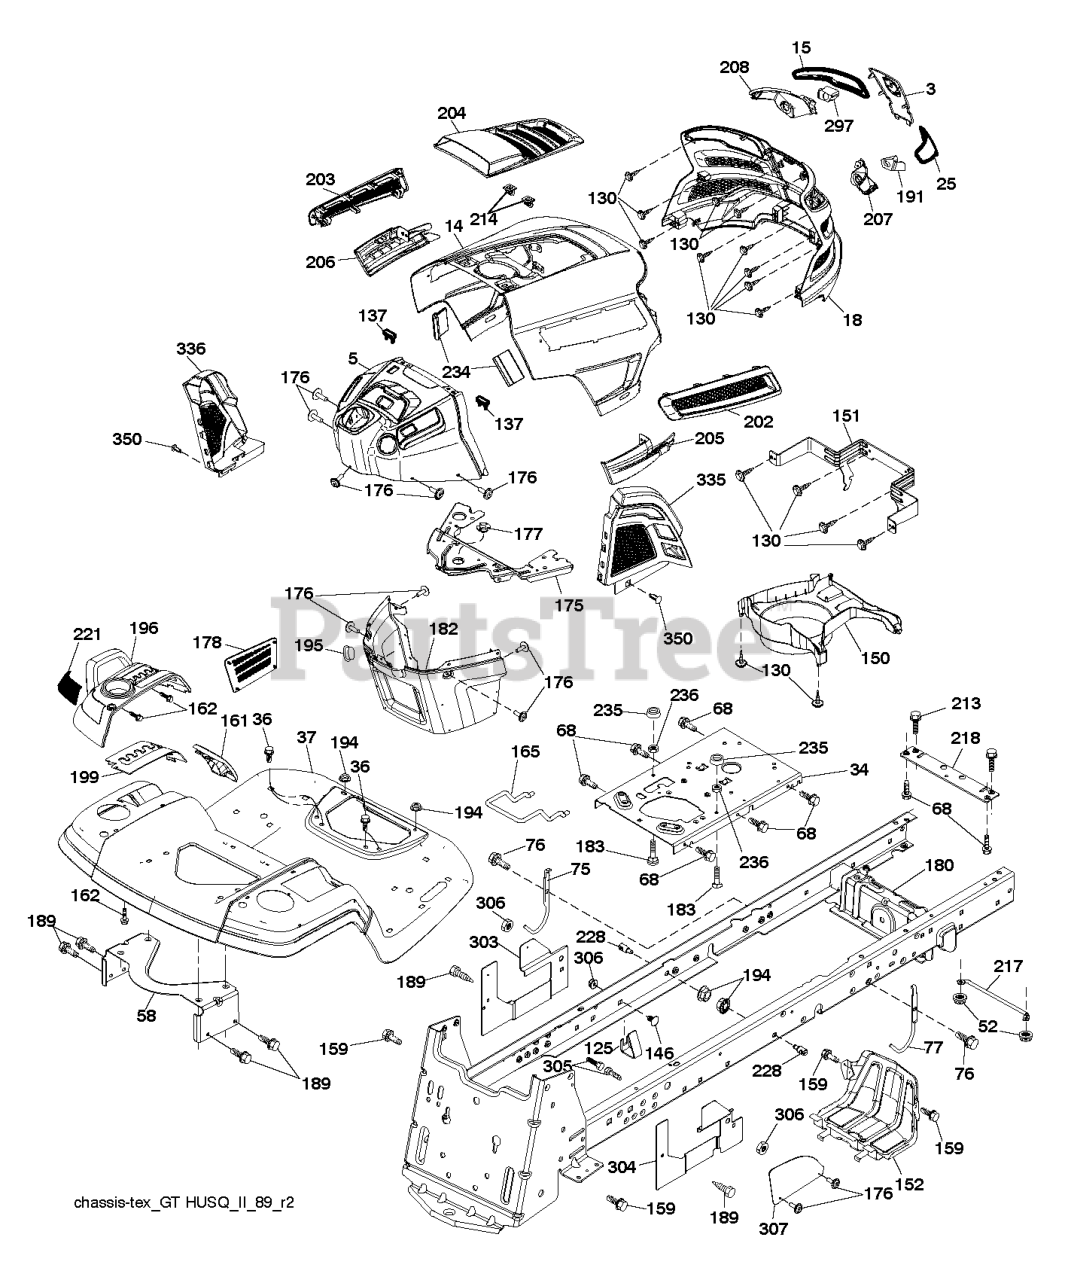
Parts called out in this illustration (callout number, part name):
3	APPLIQUE.SUBASM.GT.HUSQ.II
14	HOOD.ASM.HUSQVARNA.GT.TEX.ORAN
15	LENS.HEADLIGHT.LH.GTII.2011
18	GRILLE.SUBSTRATE.2011.
25	LENS.HEADLIGHT.RH.GTII.2011
34	PLATE.ENGINE.WELDED.CHASSIS
36	SCREW 5/16"
37	FENDER.PNT.TX.GT.CH/FW/DL.HUSQ
52	LOCKNUT
58	BRKT.SUPPORT.FNDR/TANK
68	Screw 5/16-18 x 1/2 Hex, Self Tapping 5/16-18 x 1/2
75	ROD UPSTOP
76	SCREW 3/8-16X1
77	ROD UPSTOP
125	CLIP.FUEL.LINE
130	SCREW.#10 X 0.750.BOS
137	BUMPER DASH
146	BOLT.RDHD.SHT.SQNK.3/8-16X5/8
150	AIR.DUCT.GTV2(2.54"RING HEIGHT
151	BRACKET.PIVOT.HOOD.GT.HUSQ.II
152	SHIELD.BROWNING.PNT.GT.V2
159	SCREW, 3/8-16X3/4
161	CONSOLE.WINDOW.FUEL.HUSQ.GT
162	SCREW.HI-LO.CONSOLE
165	SUPPORT.TANK.REAR.W/TEX
175	PLATE.CROSSMEMBER.HUSQ
176	SCREW.#10-24X5/8.RN.QU
177	BUSHING, STEERING
178	CARGO.ASM.NET.TXGT.W/C
180	CHASSIS.GT.SLOPED.DRAWBAR.
182	DASH.LOWER.COMMON.12V.ADAPTOR
183	BOLT.5/16-18X1-1/4 FULL THD
189	SCREW
191	INSERT.REFLECTIVE.RH.HUSQ.GTII
194	NUT LOCK HEX FLANGE 5/16-18
195	PLUG.HOLE.DASH.LOWER.12V.BLK
196	SUBASM.CONSOLE.HUSQ.GT.DECKLFT
199	PLATE.DECK.LIFT.HUSQVARNA.GT
202	VENT.SIDE.RH.GT.HUSQ.II.
203	VENT.SIDE.LH.GT.HUSQ.II.498
204	VENT.TOP.HUSQ.GT2
205	SIDE.TRIM.RH.GT.HUSQ.II
206	SIDE.TRIM.LH.GT.HUSQ.II.GRAY
207	BEZEL LIGHT.RH.GT.II.MYLAR
208	BEZEL LIGHT.LH.GT.II.MYLAR
213	BOLT
214	CLIP.RETAINER.TINNER.
217	ROD.PIVOT.HOOD
218	X-PIECE.HOOD.STOP.NON/
221	REFLECTOR.LH.TEX GT HU
228	STUD.FASTNER.W/ANTI-ROTATE
234	BUMPER.HOOD.TEX.HUSQVARNA
235	SPACER FENDER
236	NUT.CENTERLOCK.5/16-
297	INSERT.REFLECTIVE.LH.HUSQ.GTII
303	SHIELD CHASSIS LEFT
304	SHIELD CHASSIS RIGHT
305	BOLT
306	NUT LOCK FLG 3/8-16 UNC
307	SHIELD UPPER PEDAL
335	COVER.LOWER.DASH.RH.BLACK
336	COVER-LH.LOWER.DASH.GT2.BLACK
350	CLIP.X-MAS.TREE
